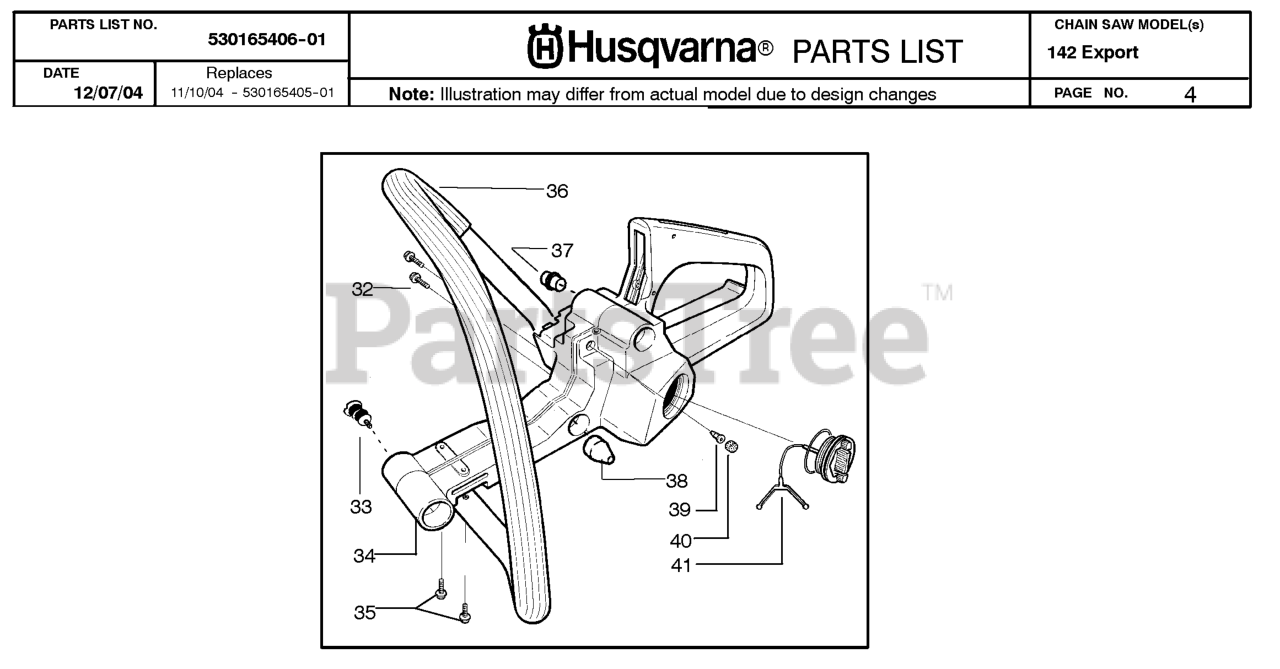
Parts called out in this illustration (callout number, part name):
36	HANDLE FRONT
37	FRONT HANDLE ISOLATOR
38	SHOCK MOUNT(X2) 36/41
39	VALVE-CHECK (DUCKBILL)
40	BRONZE PLUG
41	FUEL CAP KIT
